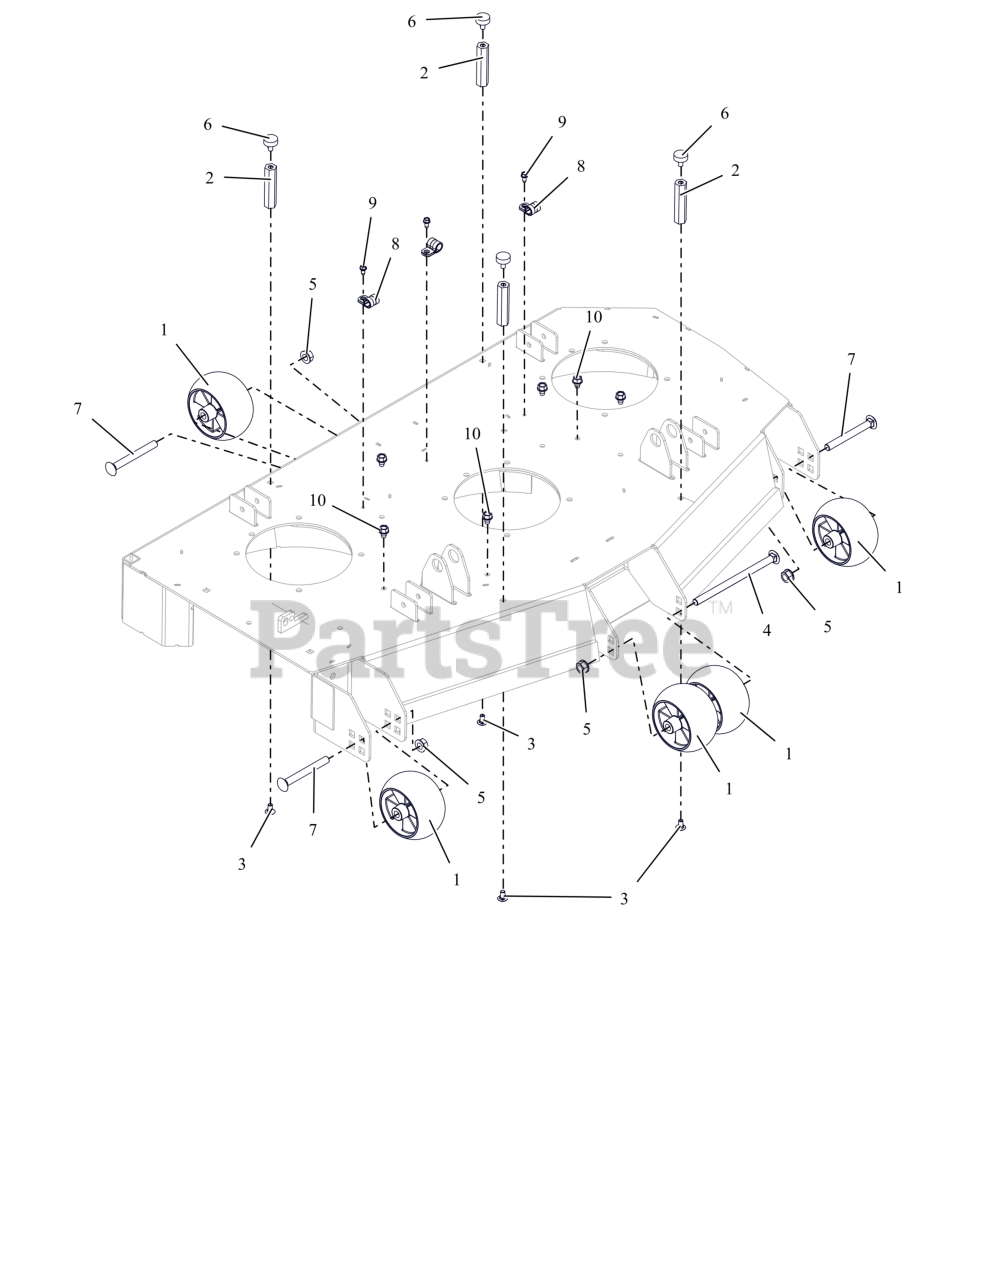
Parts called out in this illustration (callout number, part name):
1	WHEEL, ANTI SCALP - 5X3 CTR W/RIBS
2	NUT, COUPLING .312-18 X 3.375
3	BLT,RHSSN.31-18X.625 G5 ZCCP30
4	BLT-RHSN .50-13X8.00 G5 ZCC NS
5	NUT-LK-CTR-FLG .500-13 GG ZCC
6	BUMPER, RUBBER
7	BLT-RHNS .50-13X4.50 G5 ZCC NS
8	CLAMP, CUSHIONED STEEL
9	SCR-TAP .25-20X.50 HWH ZCC
10	SCR,TAP .375-16X.50 HWH TR ZCC
